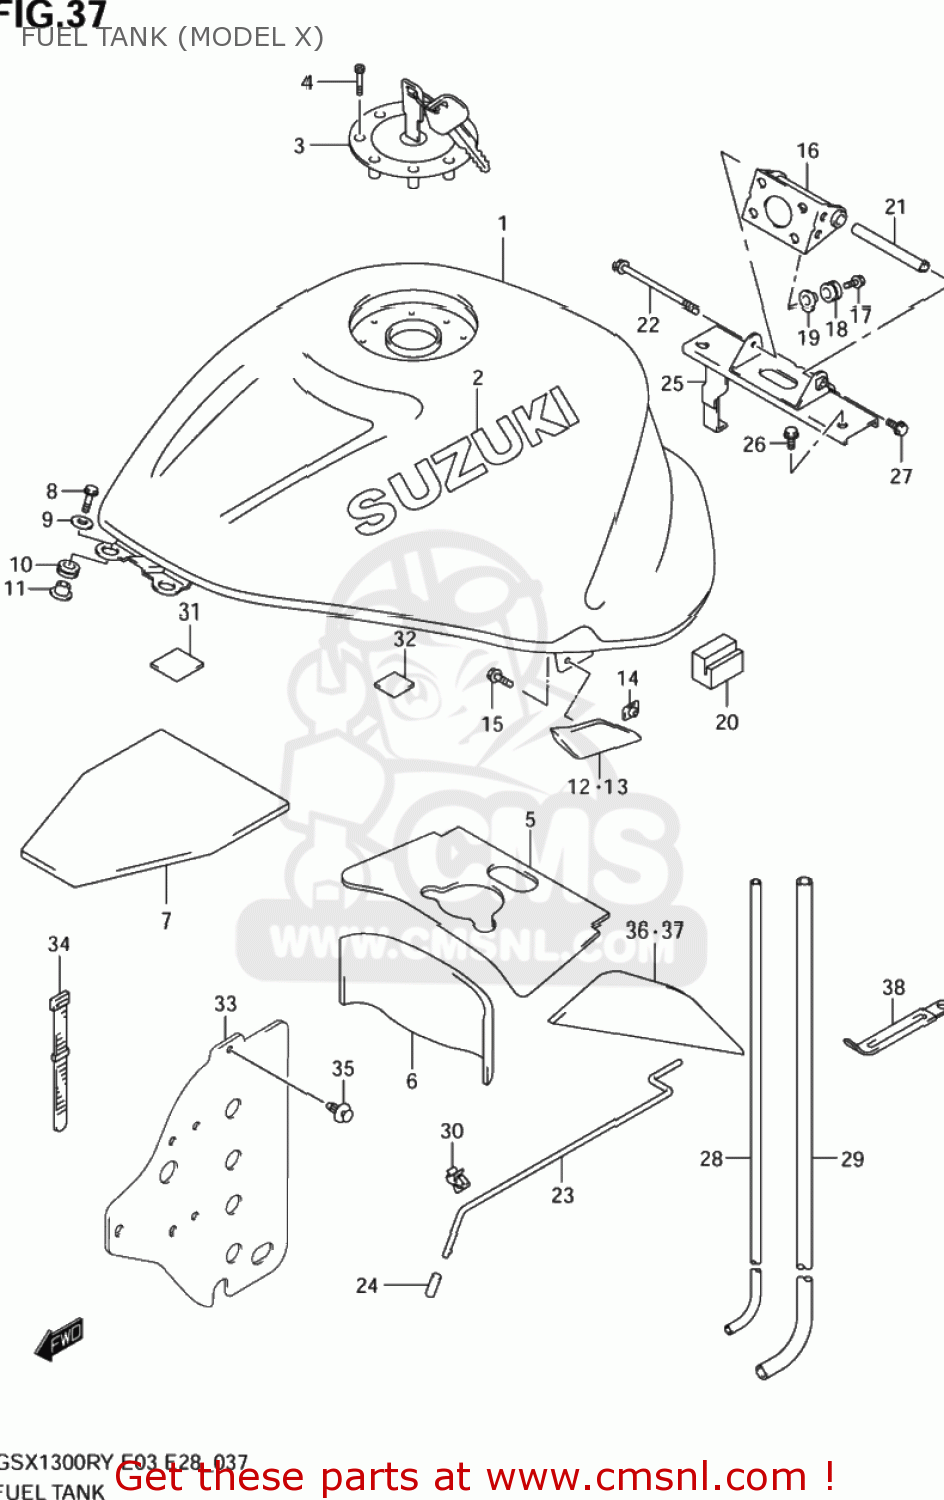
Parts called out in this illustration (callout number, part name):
1	TANK ASSEMBLY,FUEL
2	EMBLEM,FUEL TANK
3	CAP SET,FUEL TANK
4	BOLT(5X20)
5	SHIELD,FUEL TANK HEAT NO.1
6	SHIELD,FUEL TANK HEAT NO.2
7	SHIELD,FUEL TANK HEAT NO.3
8	SCREW(6X25)
9	WASHER(6.5X18X1.6)
10	CUSHION
11	WASHER
12	COVER,FUEL TANK SIDE,R
13	COVER,FUEL TANK SIDE,L
14	PLATE,FUEL TANK SIDE
15	SCREW 6X10
16	BRACKET COMP,FUEL TANK
17	BOLT(6X20)
18	CUSHION
19	WASHER
20	CUSHION,FUEL TANK SIDE
21	SPACER,FUEL TANK RR
22	BOLT
23	STAY,FUEL TANK
24	CAP,OD:11.5
25	BRACKET,FUEL TANK RR NO.2
26	BOLT
27	BOLT
28	HOSE,FUELTANK BREATHER
29	HOSE(7X11X600)
30	CLAMP
31	CUSHION
32	CUSHION,FUEL TANK COVER
33	SHEET,HEAT SHIELD RUBBER
34	CLAMP(L:165)
35	CLIP(BLACK)
36	SHIELD,FUEL TANK HEAT,R
37	SHIELD,FUEL TANK HEAT,L
38	CLAMP(L:65)
